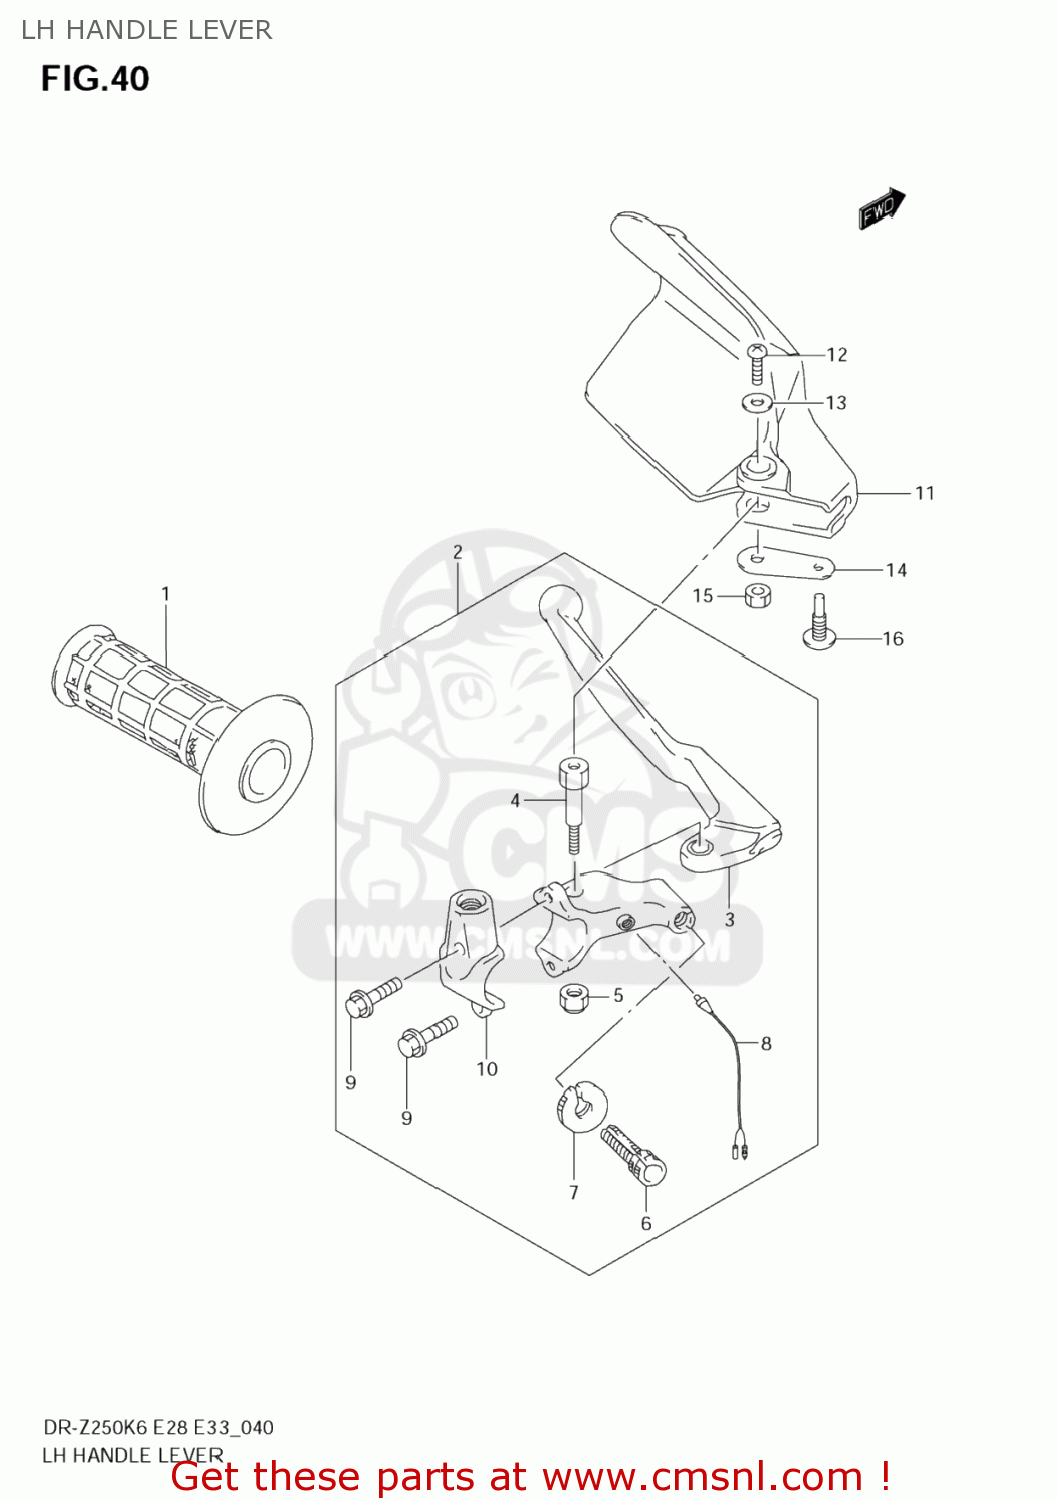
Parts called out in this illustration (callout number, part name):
1	GRIP,L
2	LEVER ASSY, CLUTCH
3	LEVER,CLUTCH
4	BOLT,LEVER PIVOT
5	NUT 6MM
6	ADJUSTER,WIRE
7	NUT,LOCK
8	SWITCH ASSEMBLY,CLUTCH
9	BOLT,BRACKET
10	BRACKET,CLUTCH LEVER HOLDER
11	COVER,KNUCKLE,L
12	SCREW
13	WASHER(5.5X16X1.2)
14	PLATE,KNUCKLE COVER,L LWR
15	NUT 6MM
16	SCREW(6X35)
